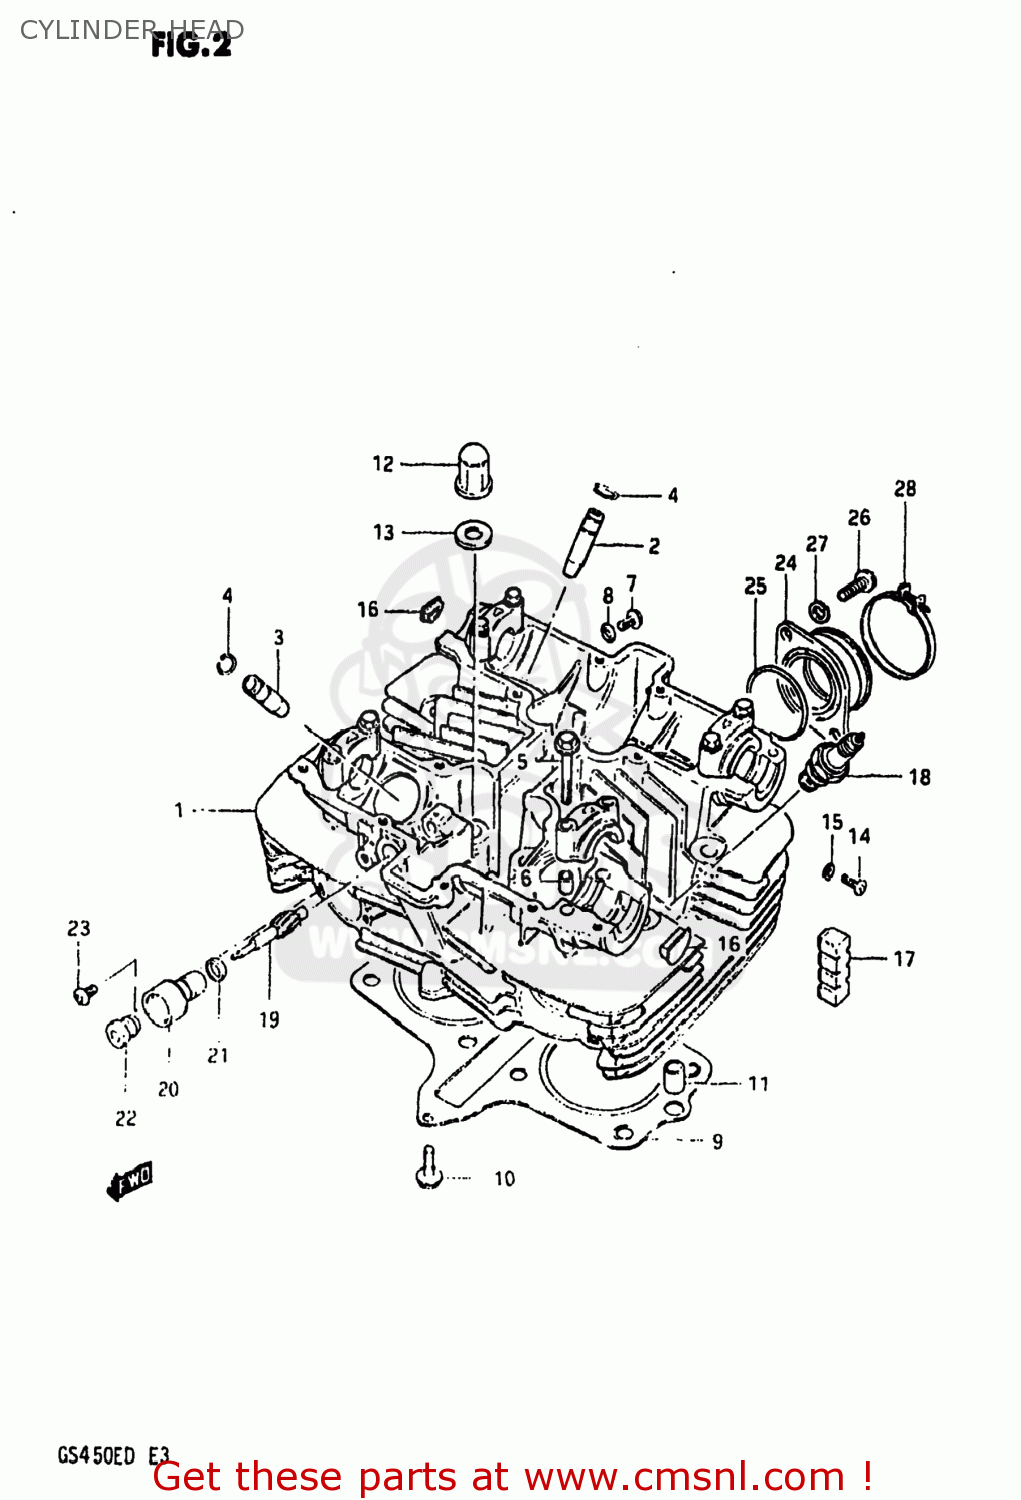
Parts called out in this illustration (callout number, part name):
1	HEAD ASSEMBLY,CYLINDER
2	GUIDE,INTAKE VALVE
3	GUIDE,EXHAUST VALVE
4	RING,SNAP
5	BOLT(6X39)
6	PIN(6.2X8X11)
7	BOLT
8	GASKET (NAS)
9	GASKET,CYLINDER HEAD (MCA)
10	BOLT
11	PIN
12	NUT
13	GASKET(10.5X22X2) (NAS)
14	SCREW
15	GASKET(5.3X9.3X1.2) (NAS)
16	PLUG
17	PAD,CYLINDER
18	SPARK PLUG
19	GEAR,TACHOMETER DRIVEN
20	SLEEVE,TACHOMETER DRIVE GEAR
21	SEAL,TACHOMETER DRIVEN
22	SEAL,OIL(5X12X8)
23	SCREW(5X12)
24	PIPE,INTAKE
25	O-RING (D:2.4 ID:39.7)
26	SCREW
27	LOCK WASHER
28	CLAMP
